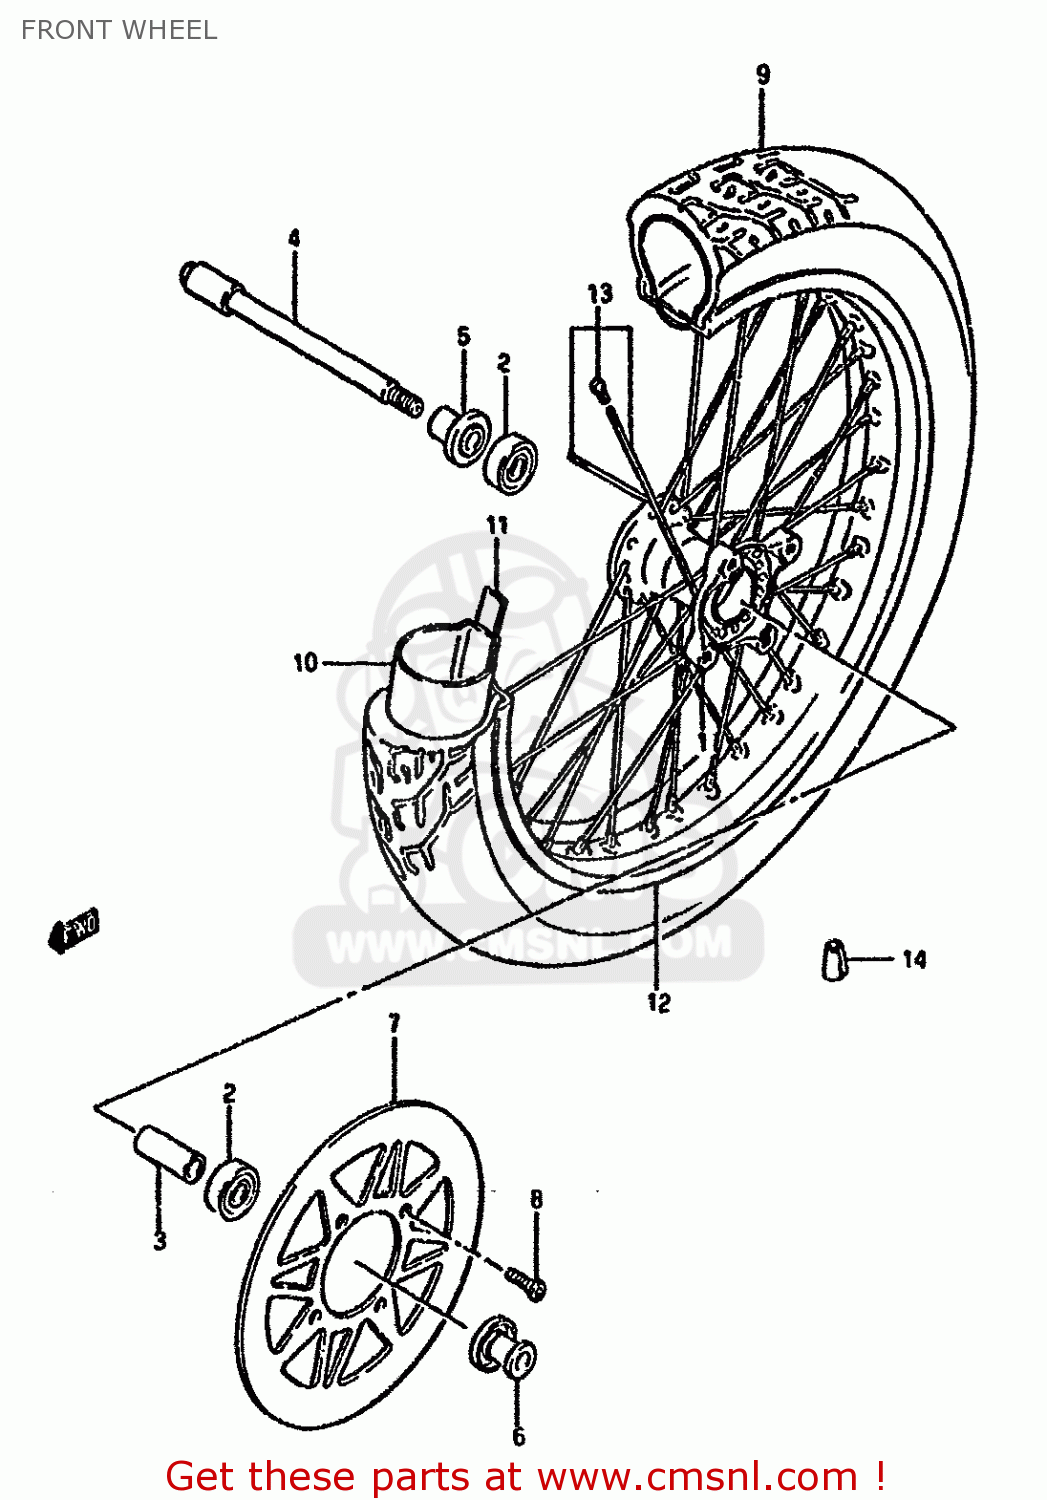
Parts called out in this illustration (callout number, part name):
1	HUB,FR WHEEL
2	BEARING
3	SPACER(15.3X21.7X56)
4	AXLE,FR
5	SPACER,FR AXLE,R
6	SPACER,FR AXLE,L
7	DISC,FR BRAKE
8	BOLT(8X25.5)
9	TIRE,FRONT
10	TUBE
11	PROTECTOR,WHL INR TUBE
12	RIM,FR WHEEL WM(2.15X19)
13	SPOKE SET,FRONT
14	BALANCER,WHEEL
